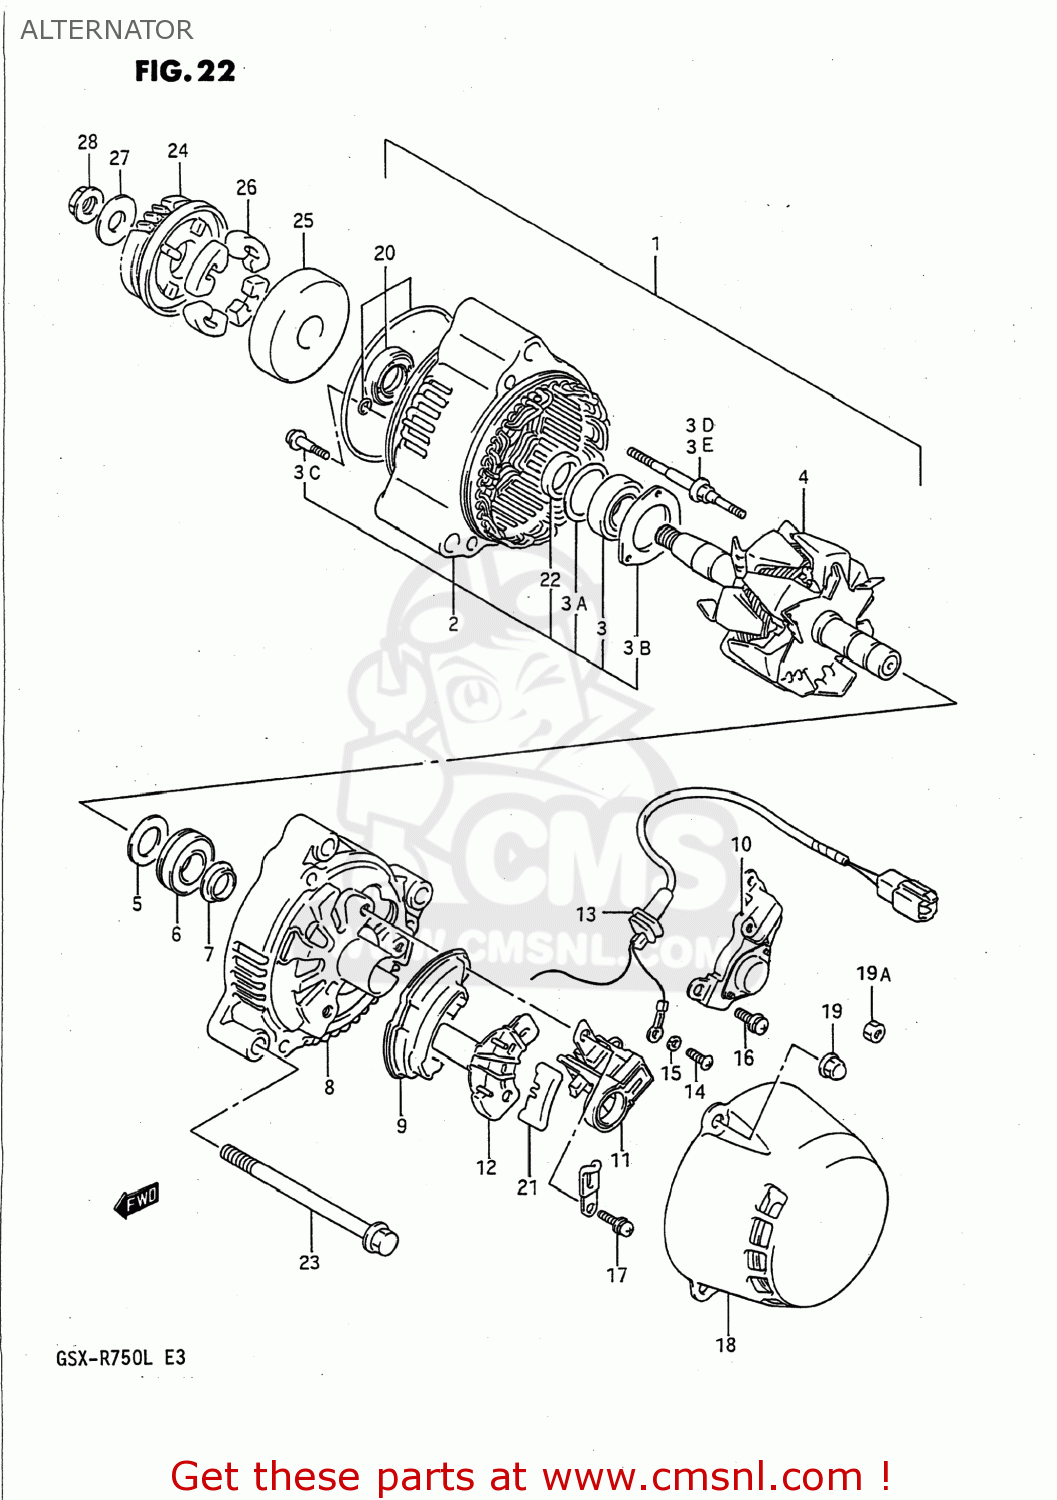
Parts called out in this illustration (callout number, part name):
1	GENERATOR ASSEMBLY
2	FRAME,DRIVE END
3	BEARING
3A	COVER,BEARING
3B	RETAINER
3C	SCREW,BEARING RETAINER
3D	STUD BOLT
3E	STUD BOLT
4	ROTOR ASSEMBLY
5	COVER (2)
6	BEARING
7	COVER(2)
8	FRAME,END
9	HOLDER,RECTIFIER
10	REGULATOR
11	HOLDER,BRUSH
12	COVER,RECTIFIER
13	WIRE,LEAD
14	SCREW
15	LOCK WASHER
16	SCREW
17	SCREW
18	COVER
19	NUT
19A	NUT ,5MM
20	SEAL SET,OIL
21	BUSH
22	SPACER
23	BOLT 8X90
24	GEAR,GENERATOR DRIVEN
25	HOUSING,GENERATOR GEAR
26	DAMPER,GENERATOR DRIVEN
27	WASHER
28	NUT
